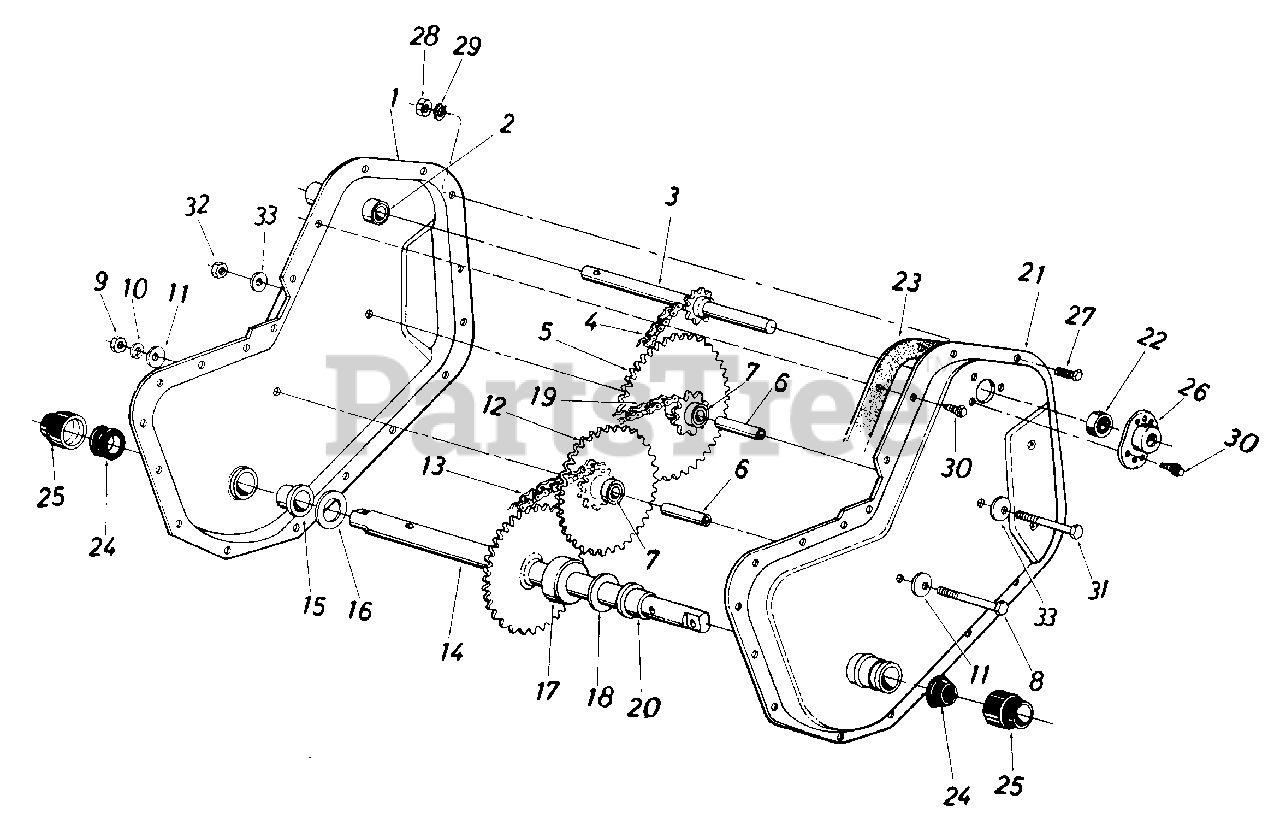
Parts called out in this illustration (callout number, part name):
1	HOUSING-CHAIN CASE
3	SHAFT ASSY-INPUT
4	#35 CHAIN 3/8 PITCH X 44 LINKS E
5	SPROCKET & HUB ASSY-9T & 36T
6	BEARING-INNER RACE
7	BEARING-SLEEVE
8	SCREW-HEX 3/8-24 X 2.50
9	NUT-HEX INS L-3/8-24
10	WASHER-LOCK-3/8
11	WASHER-BELL .3/8ID X 1.12OD X .030
12	SPROCKET & HUB ASSY-9T & 22T
13	#420 CHAIN 1/2 PITCH X 28 LINKS E
14	SHAFT ASSY-WHEEL
15	BEARING-FLANGE
16	WASHER-FL-.88 X 1.50 X .030
17	SPACER
18	WASHER-FL-.88 X 1.50 X .030
19	#420 CHAIN 1/2 PITCH X 30 LINKS E
20	BEARING-FLANGE
23	GASKET
26	HOUSING-BRG
27	SCREW-HEX 1/4-28 X .62
28	NUT-HEX 1/4-28
29	LOCK WASHER 1/4 DIA
30	SCREW-HEX WASH SF TAPP
31	SCREW-HEX
32	NUT-HEX CENTER L-5/16-18
33	WASHER-FL-.344 ID X .88 OD X .063
